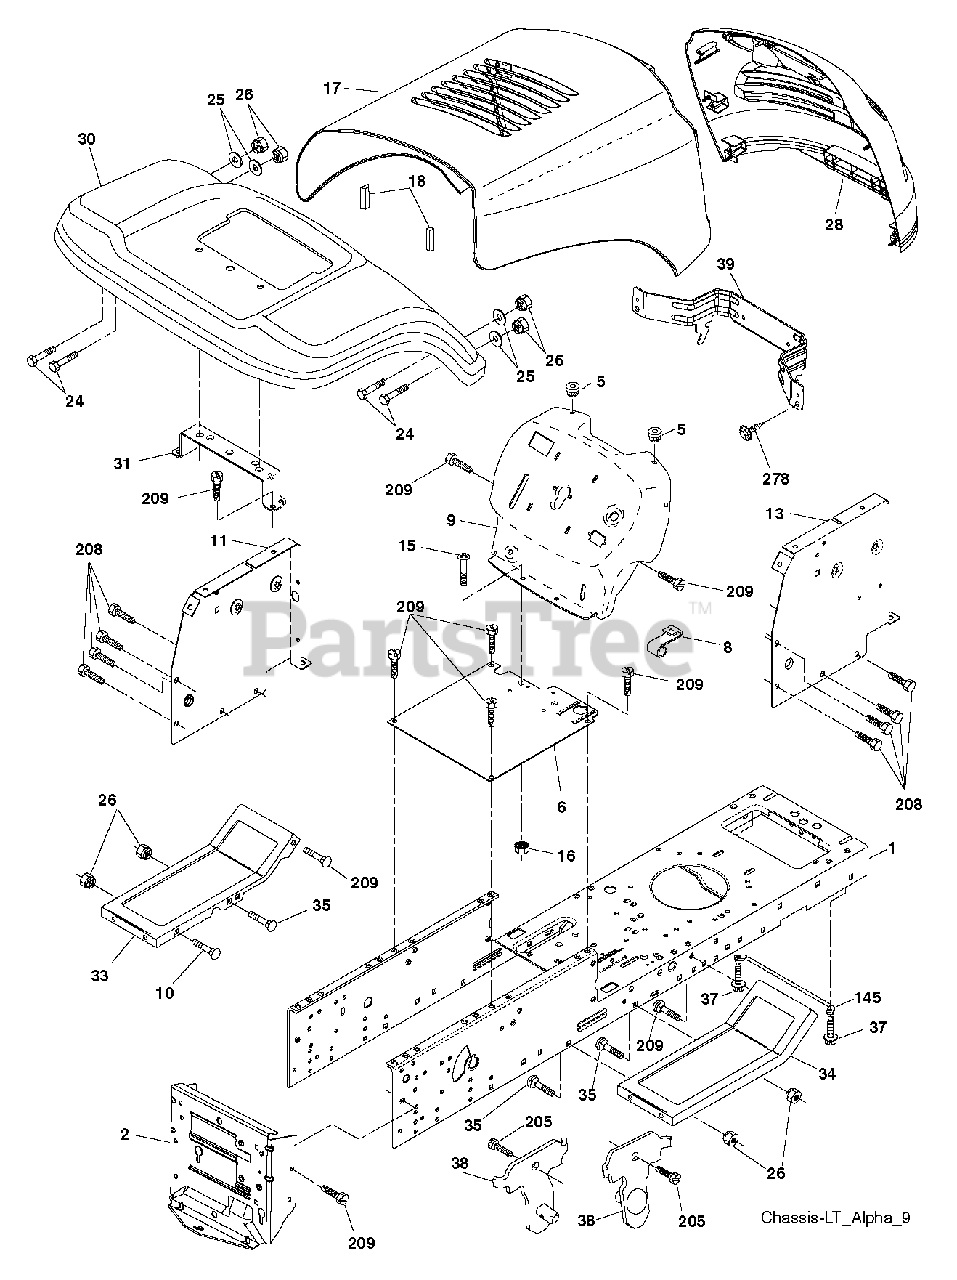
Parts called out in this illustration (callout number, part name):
1	CHASSIS
2	DRAWBAR, 12GA
5	BUMPER.RUBBER.HOOD
8	CLIP RETAINER
9	FENDER LT SH
11	PANEL.DASH.LH.LTX
18	BUMPER.HOOD.LARGE.1.75"
25	WASHER
26	NUT
28	GRILL.ALPHA.NO.LIGHTS.POULAN
30	HOOD.PNT.STEEL.ALPHA
31	BRACKET FENDER
33	FOOTREST.RH.VGT
37	SCREW LT
38	BRACKET.ASM.PIVOT.MOWER.REAR
39	BRACKET.PIVOT.ALPHA.LT
145	ROD.PIVOT.HOOD
205	SCREW LT
208	SCREW 3/8-16X1/2
209	SCREW, 3/8-16X3/4
278	SCREW.#10 X 0.750.BOS (2 2)
